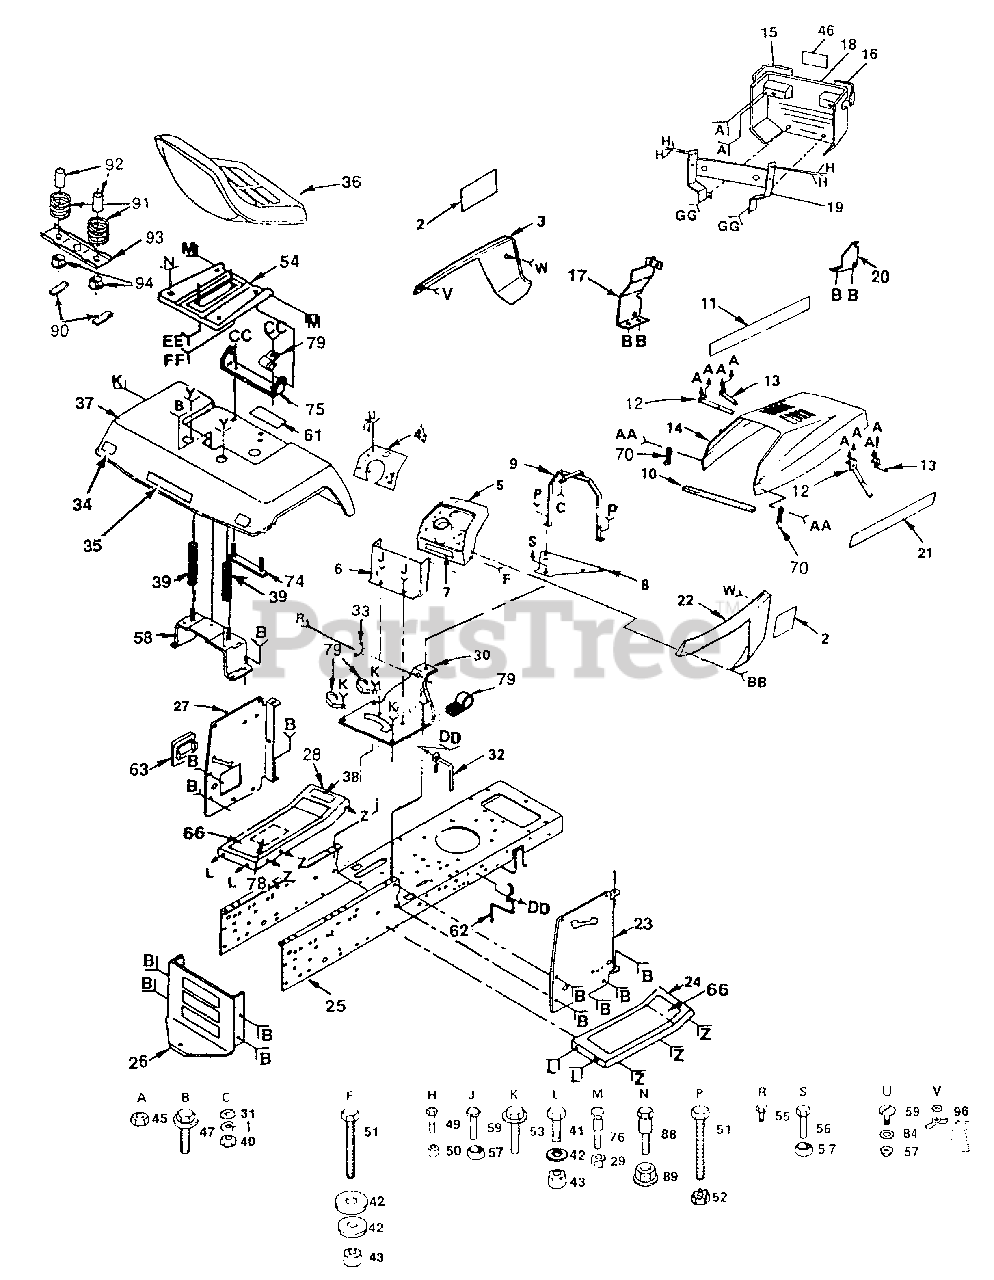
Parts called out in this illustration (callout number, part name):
2	Decal, Side Panel
3	Panel, Side L.H.
5	Dashboard
6	Dash, Lower
7	Decal, Instruction
8	Plate, Support, Battery
9	Support Assembly, Dash
10	Foam, Strip
11	Decal, Hood L.H.
12	Strap Assembly, Hinge, Rear
13	Strap Assembly, Hinge, Front
14	Hood
15	Lens, L.H.
16	Lens, R.H.
17	Bracket Assembly Frame Pivot L.H.
18	Grill Assembly
19	Support, Asm. Grill
20	Bracket Assembly Frame Pivot R.H.
21	Decal, Hood, R.H.
22	Panel, Side, R.H.
23	Panel, Dash, R.H.
24	Footrest, R .H.
26	Drawbar
27	Panel-Dash,L.H.
28	Footrest-L.H.
29	Nut-Crownlock 5/16-18
31	Washer 9/32 x 3/4 x 16 Ga.
32	Guide-Bell, Lower, Engine Pulley, L.H.
33	Bushing-Steering
34	Reflector-Taillight
35	Decal-Fender
36	Seat
38	Decal-Clutch/Brake
39	Spring, Seat
40	Nut-Hex 1/4-20
41	Bolt-Hex 3/8-16 x 3/4
42	Washer 13/32 x 13/16 x 12 Ga.
43	Nut-Crownlock 3/8-16
45	Nut, Hex, Keps 1/4 - 20
46	Decal, Grill, Husky
47	Screw-Hex Washer Hd. Thrd. Rolling 3/8 - 16 3/4 Type TT
49	Bolt - Shoulder 1/4 - 20
50	Nut - Crownlock 1/4 - 20
51	Bolt - Hex 3/8 - 16 x 1 - 1/4
52	Nut - Keps 3/8 - 16
53	Screw - Hex Washer Hd. Thrd. Forming 3/8 - 16 x 1/2 Type TT
54	Pan - Seat
55	Screw- Hex Head Sell Tapping No.10-16 x 1/2 Type B
56	Bolt - Hex 5/16 - 18 x 3/4 Gr. 5
57	Nut - Keps 5/16 - 18
58	Bracket Assembly - Fender
59	Screw - Truss Hd. 5/16 - 18 x 3/4
61	Decal - Caution
62	Guide - Belt, Lower, Engine, Pulley, R.H.
63	Cover - Access
66	Pad - Footrest
70	Latch - Hood
74	Strap Assembly-Fender
75	Bracket - Pivot, Seat
76	Bolt - Shoulder
78	Decal, Ground Drive.
79	Clip- Fuel Line
84	Washer 11/32 x 11/16 x 16 Ga.
88	Bolt Carriage 1/4 - 20 x 1-1/4
89	Nut - Hex Flange 1/4 - 20
90	Foam Strip
93	Bracket - Switch Mount
94	Snap Bushing
96	Washer, Lock 1/4 Ext/Int Tooth
